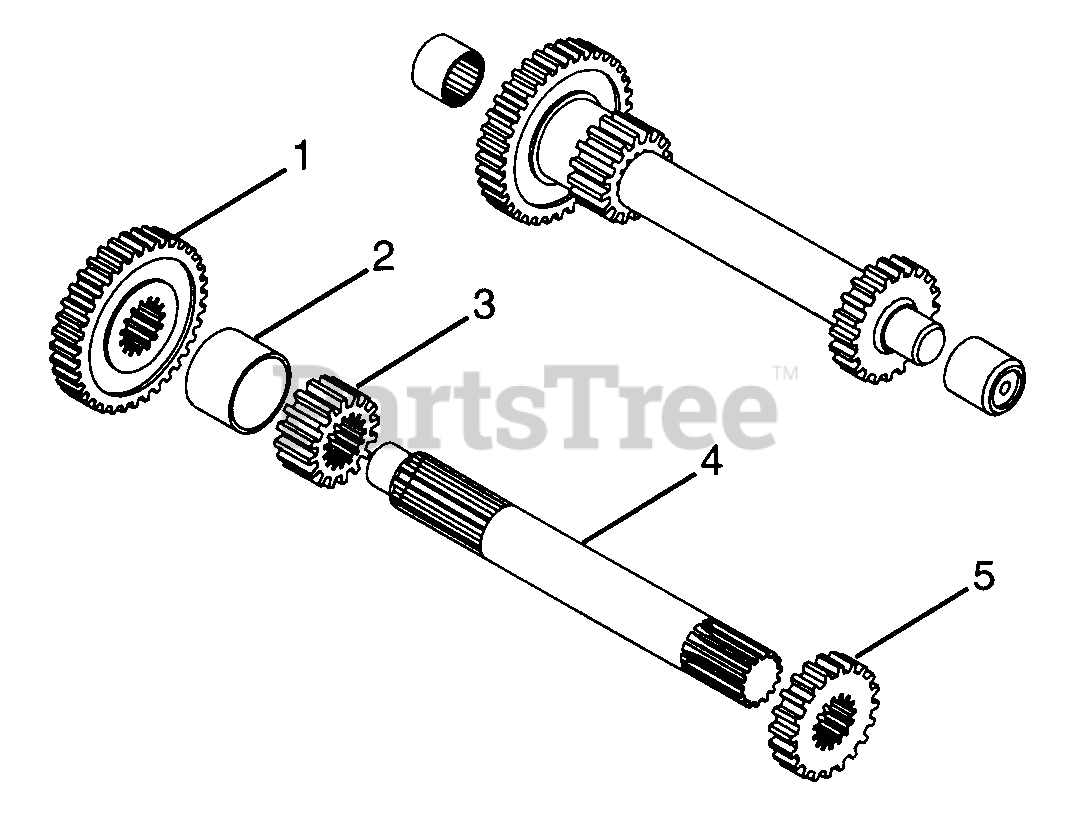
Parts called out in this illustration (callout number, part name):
1	Gear 10 DP 30 Teeth x .500
2	Bushing-Sleeve 1.03 x 1.13 x 1.13
3	Gear 10 DP 16 Teeth x .750
4	Shaft-Splined
5	Gear 10 DP 20 Teeth x .600
